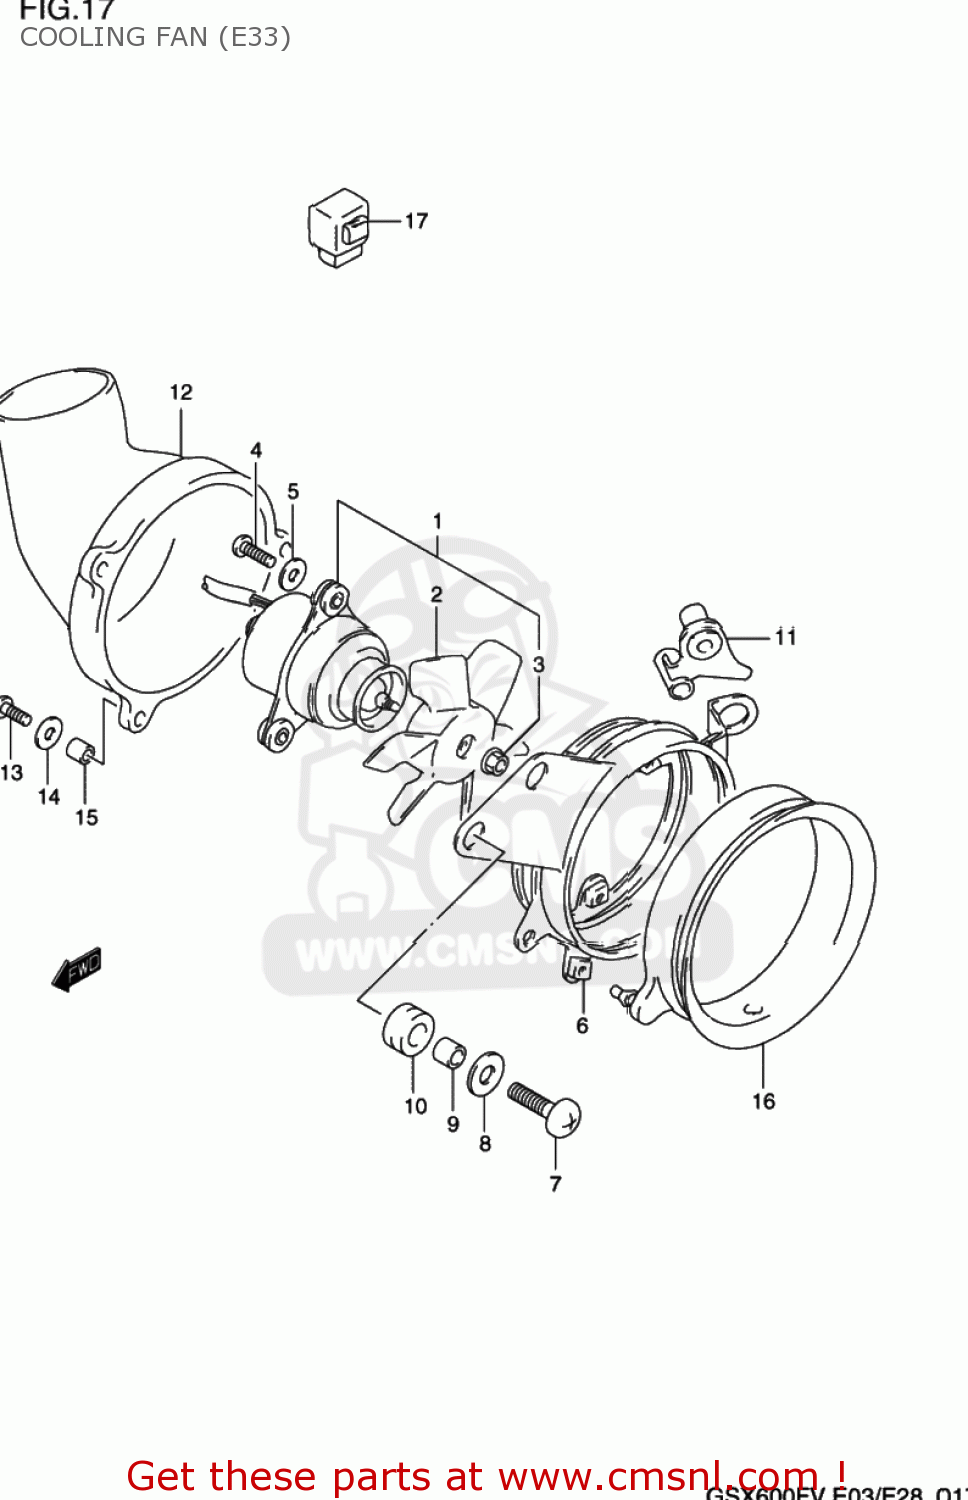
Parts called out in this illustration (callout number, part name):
1	FAN ASSY,COOLING
2	FAN
3	NUT
4	SCREW 4X16
5	WASHER (4.3X13X0.80)
6	SHROUD,FAN
7	SCREW
8	WASHER(6.5X18X1)
9	SPACER(6.5X9X6.5)
10	CUSHION
11	BRACKET,FAN SHROUD
12	DUCT,FAN COOLING NO.1
13	SCREW
14	WASHER (4.3X13X0.80)
15	SPACER(4.5X6.5X5)
16	DUCT,FAN COOLING NO.2
17	CONTROLLER ASSY,FAN MOTOR
